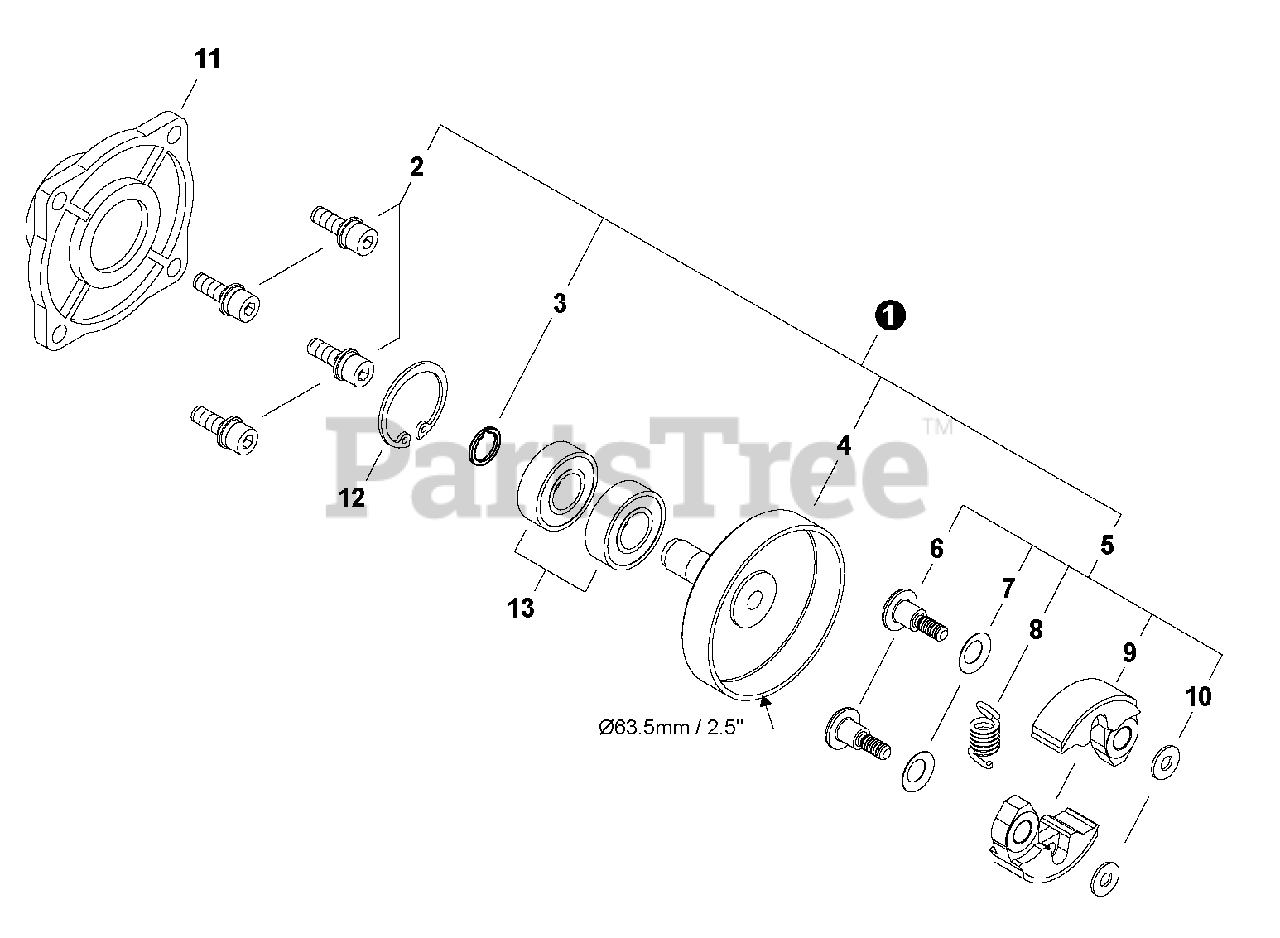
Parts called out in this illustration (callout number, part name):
1	Clutch Kit
2	Bolt M5x16
3	Ring, Snap dia.12
4	Drum, Clutch
5	Dlutch Assy
6	Bolt, Clutch
7	Washer, Spring
8	Spring, Clutch
9	Shoe, Clutch
10	Washer 6mm
11	Case, Clutch
12	Ring, Snap dia.28
13	Bearing, Ball 6001 DDU C3
